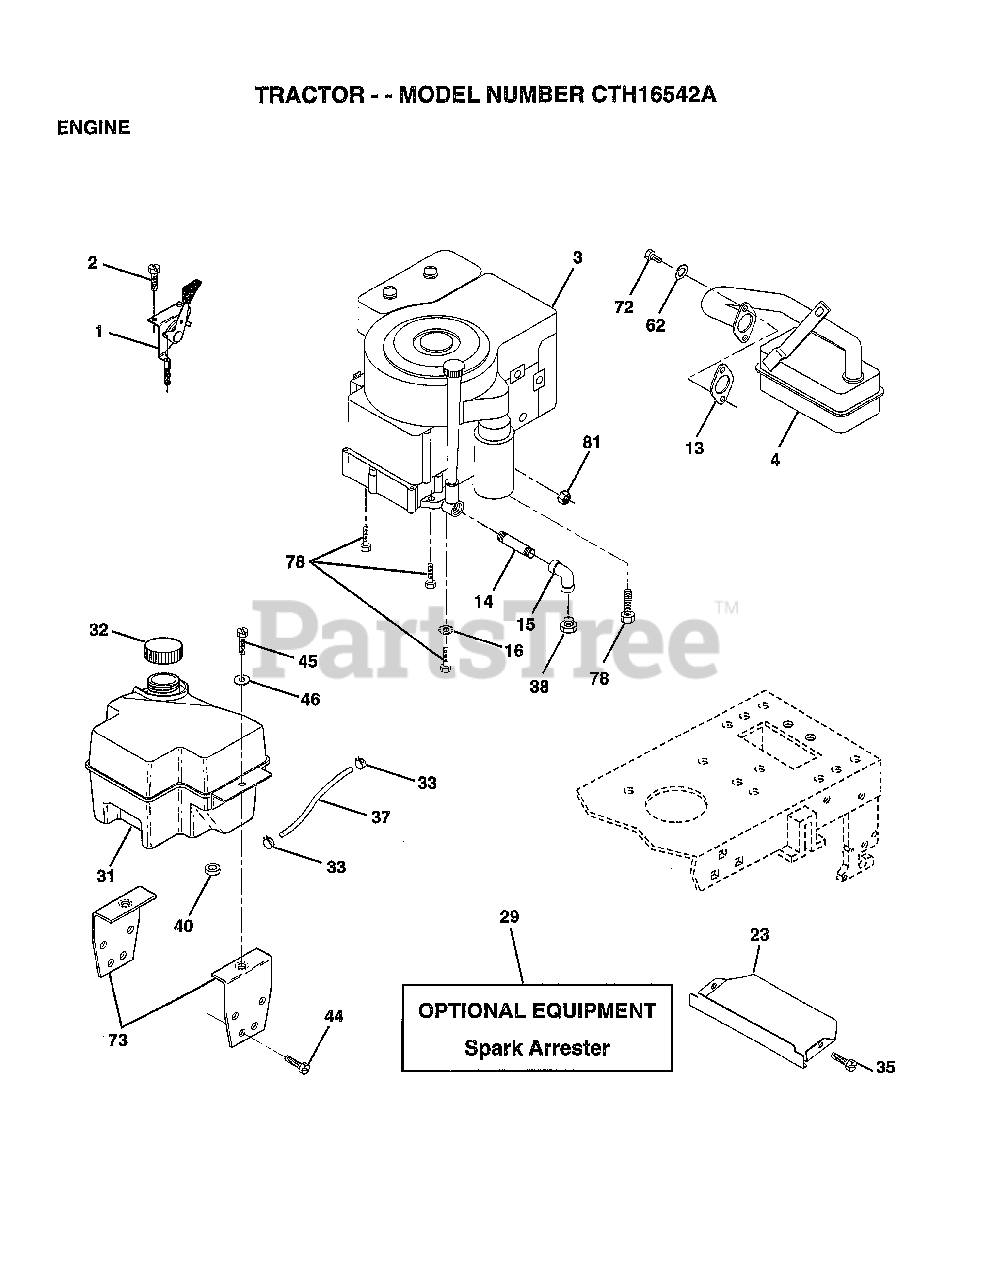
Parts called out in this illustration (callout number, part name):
1	CONTROL.THTL.19.6
2	SCREW LT
4	MUFFLER
13	GASKET ENG 1 313 LD TIN PLATED
14	PIPE NIPPLE
15	ELBOW
16	LOCKWASHER
23	SHIELD.BRN/DBR.GD
31	TANK.FUEL.FRONT.
32	CAP ASM FUEL
33	HOSE CLAMP
35	SCREW
37	LINE FUEL
44	SCREW
45	SCREW HEX CRT
46	WASHER
62	LOCKWASHER
72	SCREW
73	BRACKET.SUPT.TANK
78	SCREW
81	NUT
